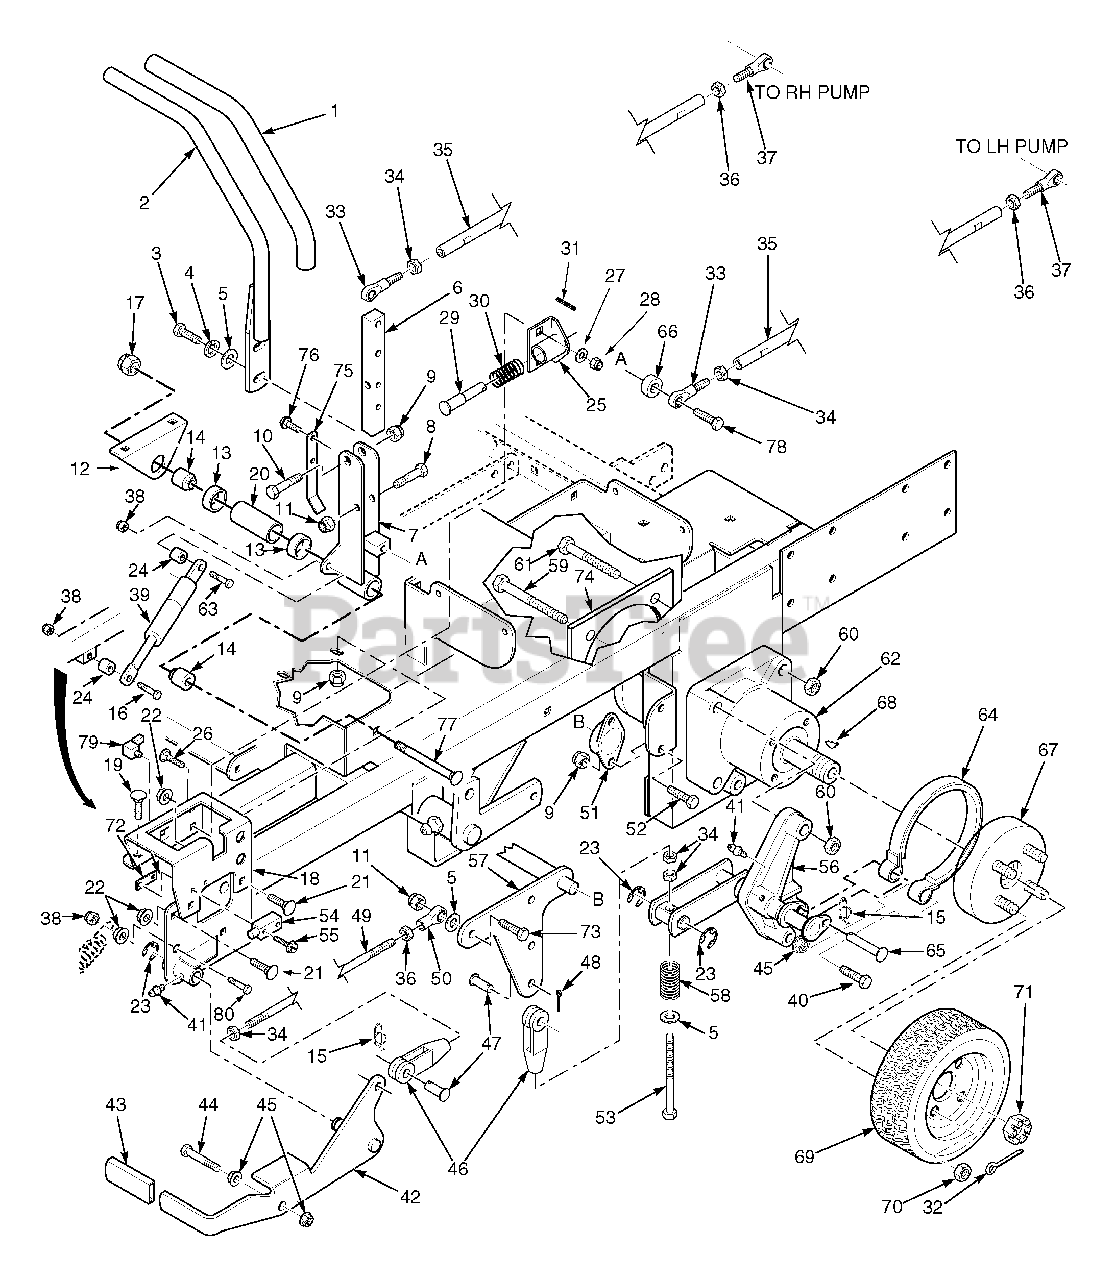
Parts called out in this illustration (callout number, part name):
1	Grip, Handle Bar
2	Handle Bar
3	Bolt, Hex Head 3/8-16 x 1-1/4"
4	Lockwasher, 3/8"
5	Flatwasher. 3/8" (.391 x .938 x .105)
6	Bar, Control Lever
7	Control Lever Weldment, LH
8	Bolt, Hex Head 5/16-18 x 2"
9	Nut, Hex Elastic Stop 5/16-18
10	Bolt, Hex Head 3/8-16 x 2"
11	Nut, Hex Elastic Stop
12	Mount, Control Linkage
13	Ball Bearings, Neutral Return
14	Spacer
15	Pin, Rue Cotter 3/8 Dia.
16	Bolt, Hex Head, 5/16-18 x 2.75 Zinc.
17	Nut, Hex Elastic Stop 5/8-11
18	Bracket, Control Lever LH
19	Bolt, Carriage 5/16-18 x 1"
20	Spacer, Bearing
21	Bolt, Carriage 5/16-18 x 3/4"
22	Nut, Hex Serrated Flange 5/16-18
23	Ring, Retaining 5/8" External "E"
24	Spacer
25	Bracket, Neutral Return
26	Bolt, Carriage 1/4-20 x 3/4"
27	Flatwasher, 1/4" (.312 x .750 x .065)
28	Nut, Hex Elastic Stop 1/4-20
29	Pin, Retaining Spring
30	Spring
31	Roll Pin, Spring 5/32 x 3/4"
32	Pin, Cotter 9/16 x 1-1/2"
33	Rod End, Male 3/8-24 RH Thread
34	Nut, 3/8-24 RH Thread
35	Tube, Control Link
36	Nut, Hex 3/8-24 LH Thread
37	Rod End, Male 3/8-24 LH Thread
38	Locknut, 5/16-18, Elastic Stop
39	Gas Damper
40	Bolt, Hex Head 3/8-16 x 2-1/2"
41	Grease Fitting
42	Lever, Parking Brake
43	Grip, Parking Brake
44	Bolt, Hex Head 3/8-16 x 2-3/4"
45	Nut, Hex Serrated Flange 3/8-16
46	Clevis, Traction Control
47	Pin, Clevis 3/8-16 x 1-1/16"
48	Pin, Cotter 3/32 x .75
49	Rod, Parking Brake
50	Rod End, LH Thread
51	Bushing, Self Align
52	Bolt, Hex Head 5/16-18 x 3/4"
53	Bolt, Hex Hd 3/8-24 x 5-1/4", 23/4" Thrd
54	Switch
55	Screw, Hex SLTD WSHR Head #10 32 x 3/4"
56	Brake Linkage, LH
57	Bellcrank, Brake Actuator
58	Spring
59	Bolt, Hex Head 1/2-13 x 3-3/4"
60	Locknut, Hex 1/2-13 Center Lock
61	Bolt, Hex Head 1/2-13 x 2-1/2"
62	Wheel Motor, Ross
63	Bolt, Hex Head, 5/16-18 x 1.75, Zinc
64	Brake Band Assembly
65	Pin, Clevis 3/8" Dia. x 1.93"
66	Spacer
67	Wheel Hub/Brake Drum Assembly
68	Key, Woodruff 5/16 x 1"
69	Wheel Assembly 24 x 12-12 Turf Master
70	Lug Nut, 1/2-20
71	Nut, Hex Castle
72	Threaded Plate
73	Bolt, Hex Head 3/8-16 x 1-1/2"
74	Plate Weldment, Motor Backing
75	Actuator Switch
76	Bolt, Hex Serrated Flange 5/16-18 x 3/4"
77	Bolt, Carriage 3/8-16 x 4-3/4"
78	Bolt, Hex Head 3/8-16 x 1"
79	Switch
80	Bolt, Hex Head 3/8-16 x 1-1/4" Grade 8
